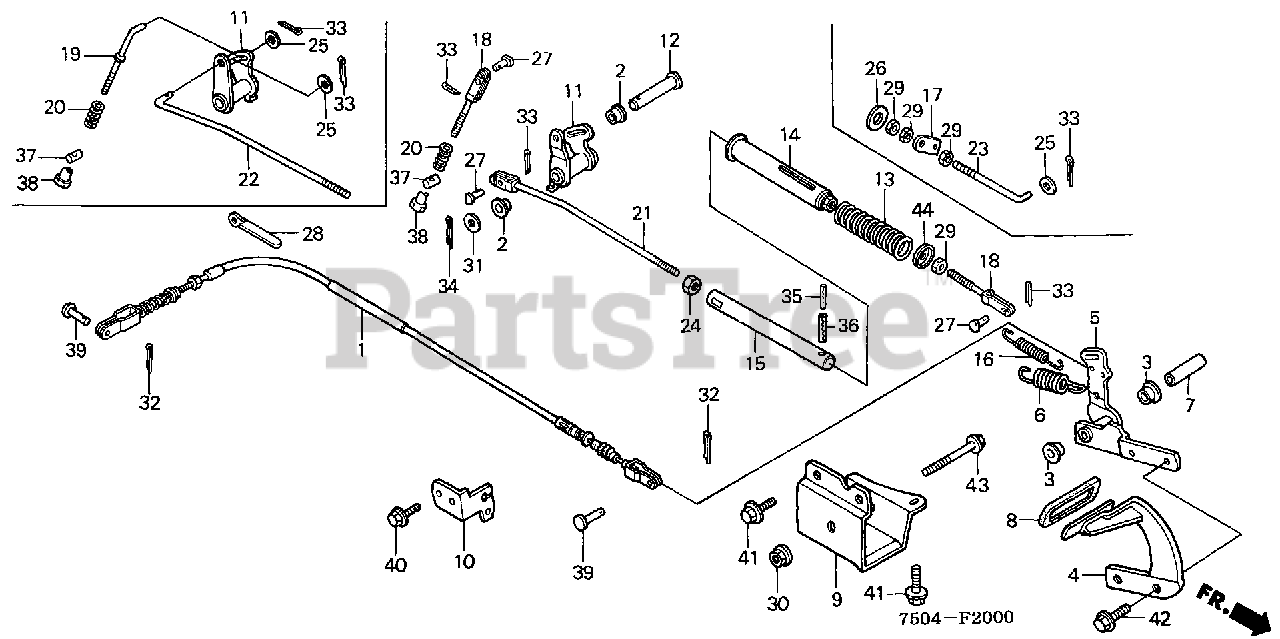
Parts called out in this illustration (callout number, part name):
1	CABLE, FOOT CLUTCH
2	BUSH, PINION GEAR
3	BUSH, PEDAL
4	PEDAL, BRAKE
5	ARM, BRAKE PEDAL
6	SPRING, BRAKE PEDAL (NOT AVAILABLE)
7	COLLAR, PEDAL
8	COVER, BRAKE PEDAL
9	BRACKET, BRAKE PEDAL
10	HOLDER, BRAKE CABLE
11	ARM, BRAKE ROD
12	PIN (12MM)
13	SPRING, BRAKE LOAD SETTING
14	PIPE, BRAKE SPRING SETTING
15	SHAFT, SPRING SET
16	SPRING, BRAKE DAMPER (NOT AVAILABLE)
18	ROD A, RR. BRAKE
20	SPRING A, BRAKE ROD
21	ROD B, FOOT BRAKE
24	NUT, TIE ROD
27	PIN (5.3X17)
28	CLIP (2X74)
29	NUT, HEX. (6MM)
30	NUT, FLANGE (10MM)
31	WASHER, PLAIN (12MM)
32	PIN, COTTER (1.6X12)
33	PIN, COTTER (2.0X15)
34	PIN, COTTER (3.0X45)
35	PIN, SPRING (3X28)
36	PIN, SPRING (5X28)
37	JOINT, BRAKE ARM
38	NUT B, BRAKE ROD ADJUSTING
39	PIN B, BRAKE ROD JOINT
40	BOLT, FLANGE (6X16)
41	BOLT, FLANGE (8X14)
42	BOLT, FLANGE (8X25)
43	BOLT, FLANGE (10X80)
44	WASHER, PLAIN (20MM)
44	WASHER, BRAKE SPRING SETTING
